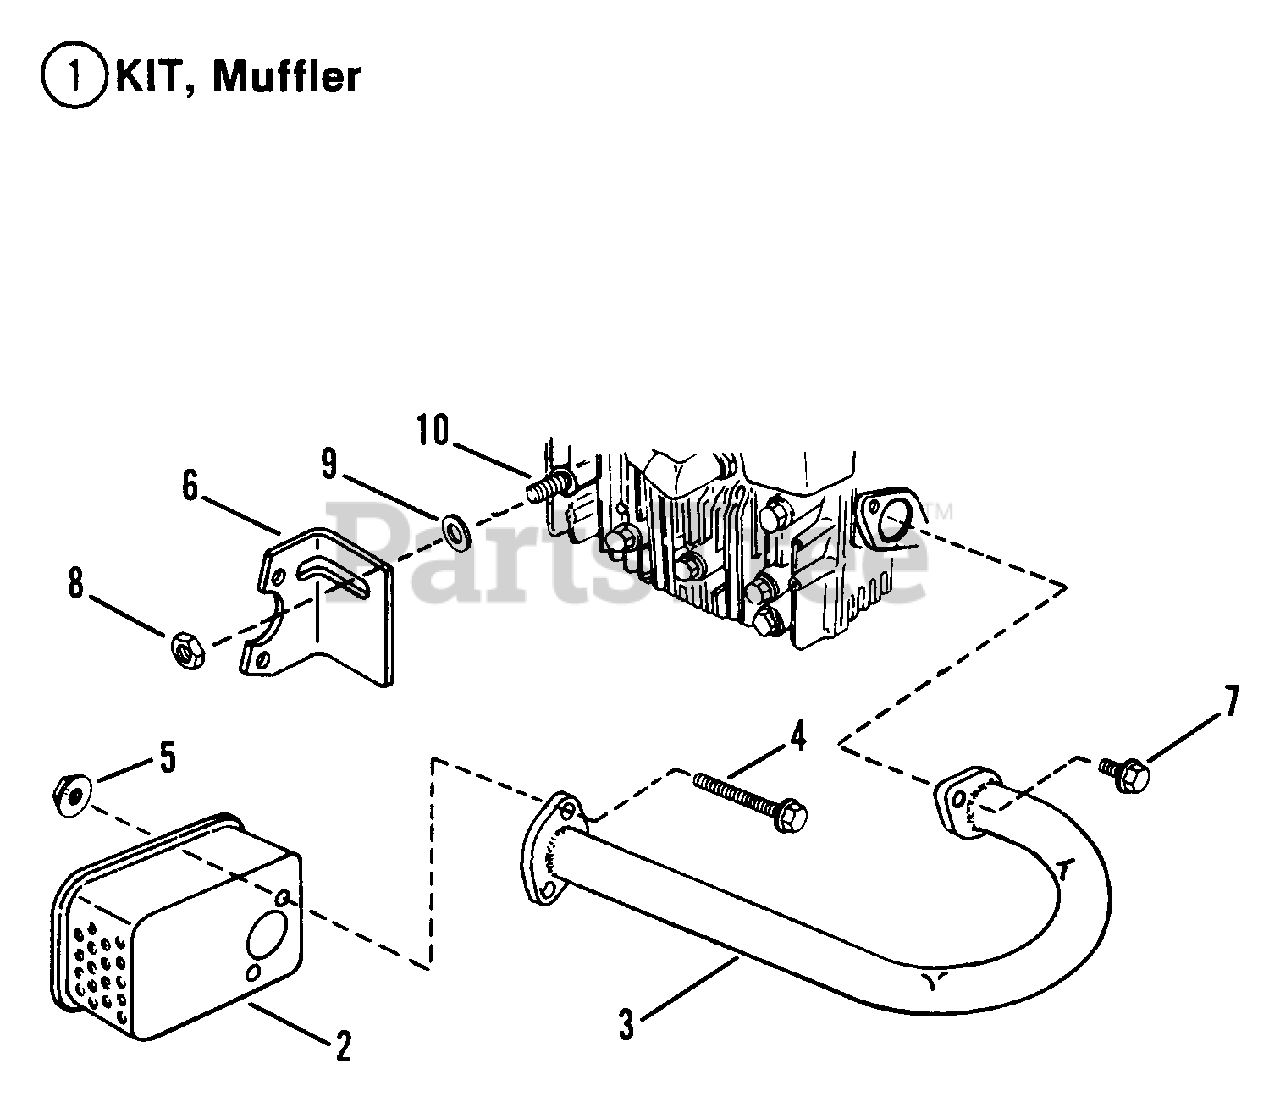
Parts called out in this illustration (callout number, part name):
1	KIT, Muffler
2	MUFFLER
3	TUBE, Exhaust
4	SCREW, 5/16-18 x 3" Hex Head Cap
5	NUT, 5/16-18 Hex Flange Lock
6	BRACKET, Muffler
7	SCREW, 1/4-20 x 5/8" Hex Head Cap
8	NUT, 5/16-18 Hex
9	WASHER, 21/64 Flat
10	STUD, Cylinder Head
